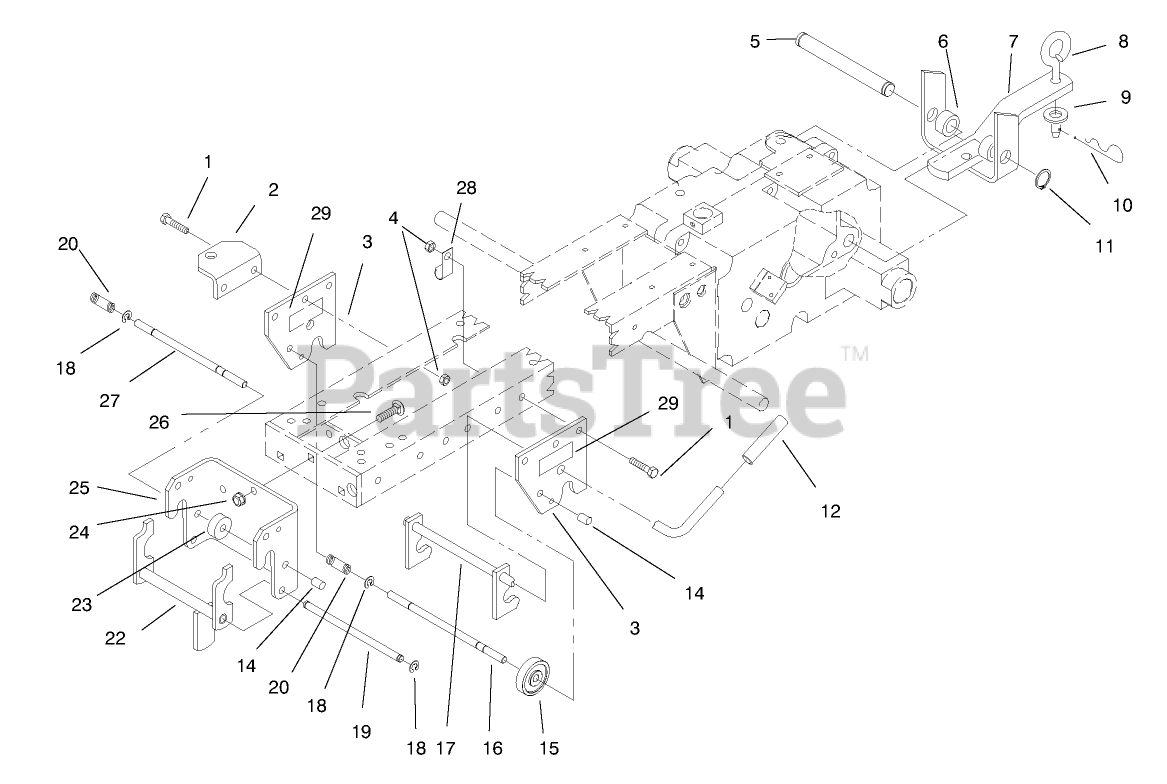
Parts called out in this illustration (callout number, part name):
1	SCREW-HH
3	PLATE-HITCH
4	NUT-HEX
5	PIN-STATIONARY HITCH
6	SPACER
8	PIN-TOOL
9	WASHER-FLAT
10	PIN-HAIR
11	E-RING
12	GRIP
14	CAP-ROD, PLUNGER
16	ROD-LOCK
17	MID HITCH ASM
18	RING-RETAINING
19	ROD-LATCH PIVOT
20	SPRING
22	LATCH
24	NUT-LOCK, NI
25	HITCH-FRONT
26	BOLT-CARR
27	ROD-LOCK
28	CLIP
29	DECAL-ATTACH A-MATIC
